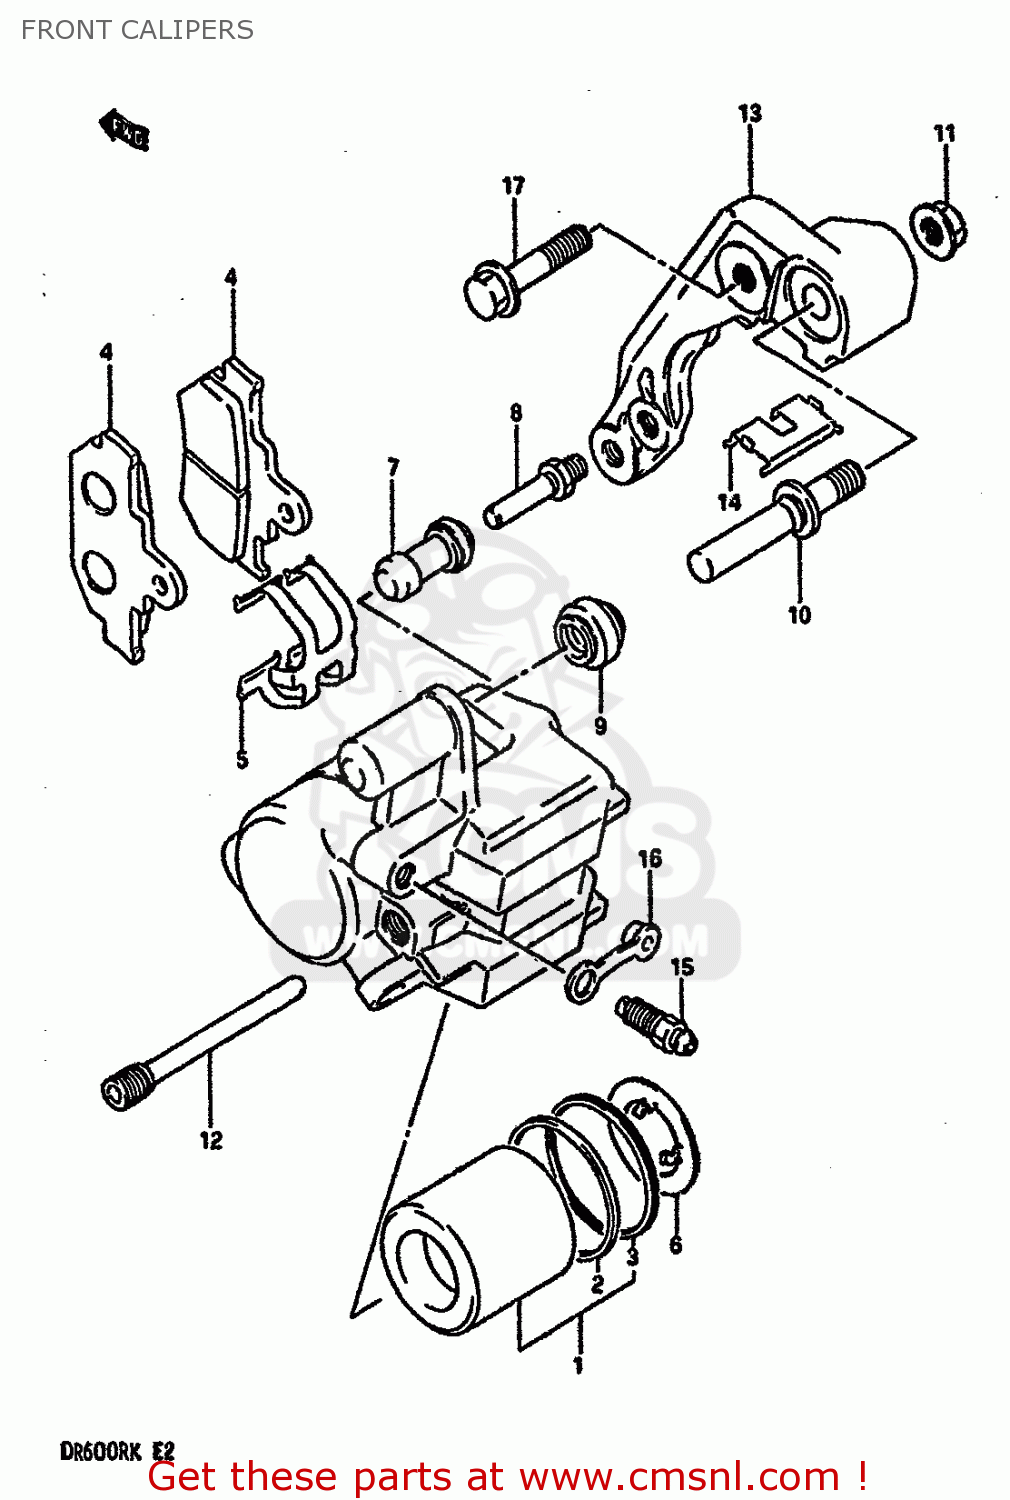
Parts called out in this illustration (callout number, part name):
1	PISTON SET,CALIPERS
2	SEAL,PISTON
3	DUST SEAL,PISTON
4	PAD
5	SPRING,PAD
6	SHIM
7	BOOT
8	PIN,BOLT
9	BOOT
10	PIN,SLIDE
11	NUT,SLIDE PIN
12	PIN,HANGER
13	BRACKET
14	RETAINER
15	BLEEDER
16	CAP,BLEEDER
17	BOLT(8X35)
